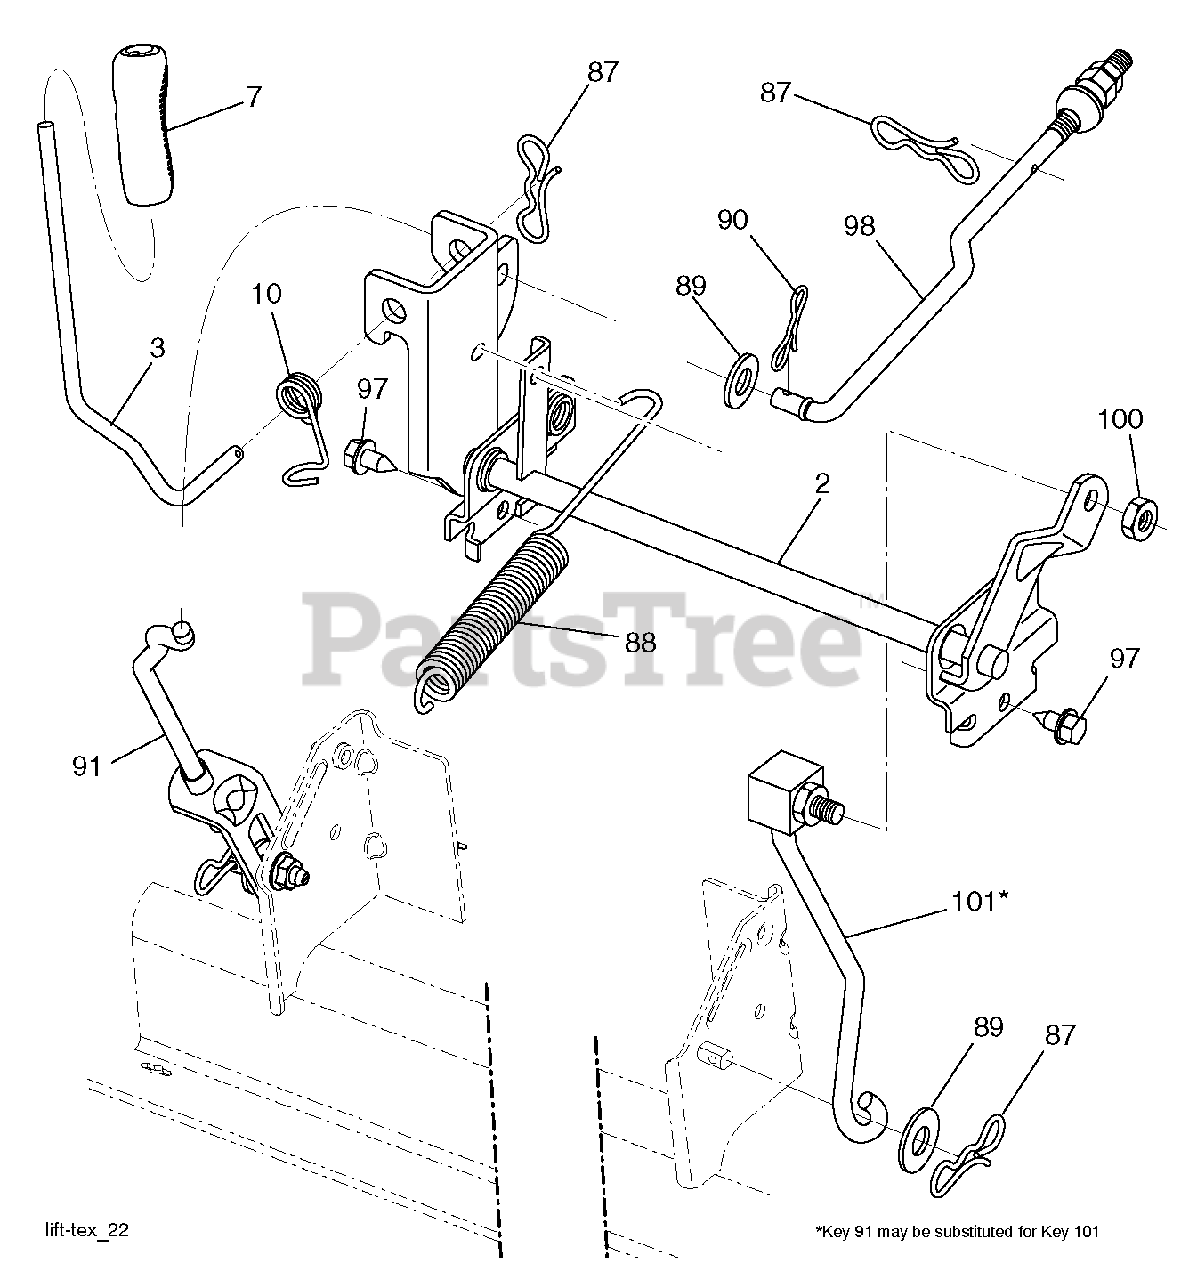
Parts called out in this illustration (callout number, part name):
2	SHAFT.ASM.CROSS.LIFT
3	LEVER.LIFT.HANDLE.LT
7	GRIP.HANDLE.LIFT.PVC.BLACK
10	SPRING.TORSION.LIFT.HANDLE
87	PIN.COTTER.7/16.BOW TI.
88	SPRING.LIFT.ASSIST
89	WASHER.CLEAR.ZINC
90	PIN.COTTER.5/16.BOW TI
91	LINK.ASM.LIFT.REAR
97	SCREW, 3/8-16X3/4
98	LINK.ASM.SUSP.FRONT.MW
100	LOCKNUT
101	LINK.ASM.LIFT.FIXE.38/42/46"
